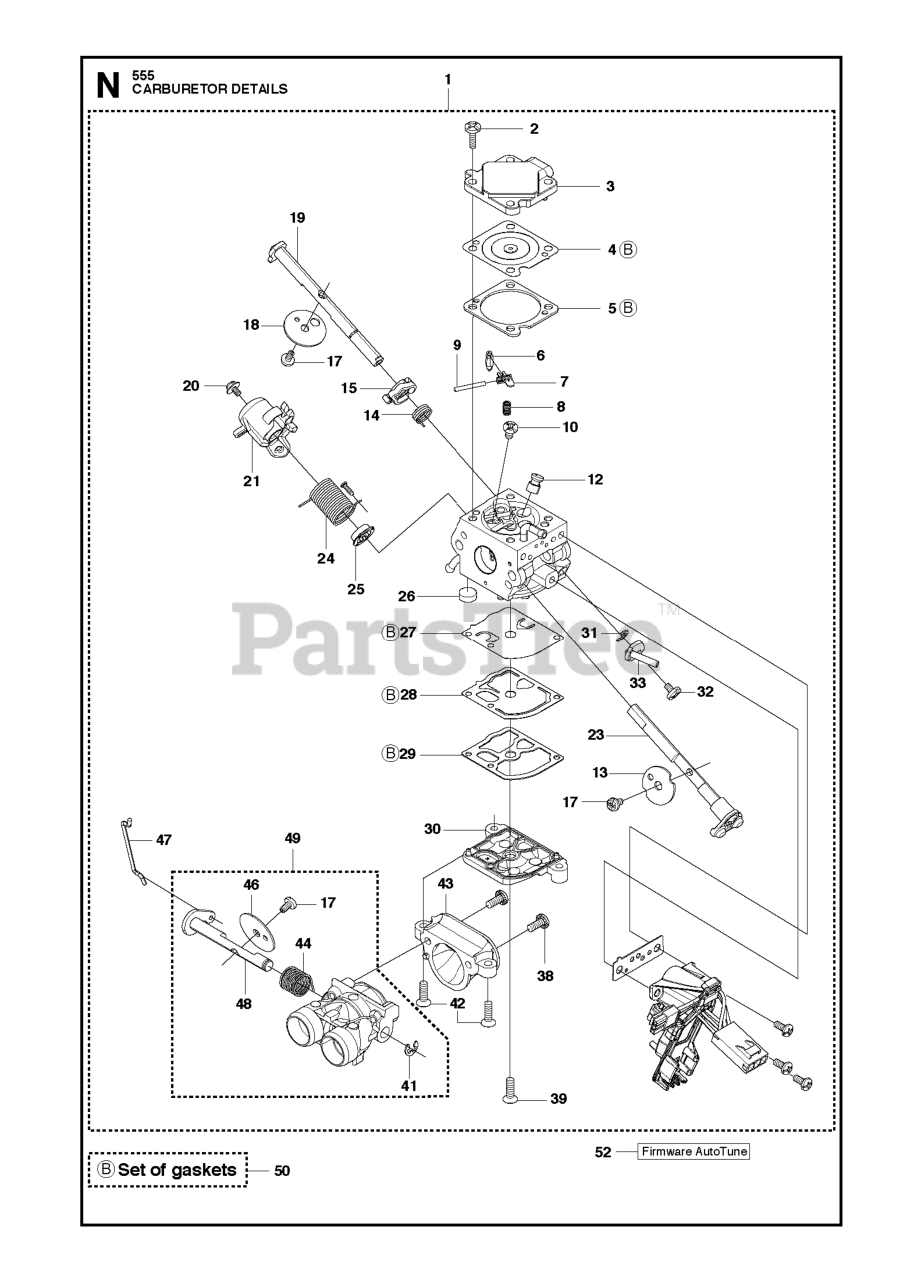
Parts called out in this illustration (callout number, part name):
1	CARBURETOR KIT 555 AUTOTUNE
1	CARBURETTOR KIT 60CC
6	INLET NEEDLE
9	PIN RETAINING SCREW
12	MAIN NOZZLE
13	VALVE
13	THROTTLE VALVE
18	CHOKE VALVE
19	SHAFT ASSY
21	THROTTLE LEVER
23	THROTTLE SHAFT
27	PUMP DIAPHRAGM
33	CHOKE LEVER
46	THROTTLE FLAP
48	SHAFT ASSY
49	THROTTLE VALVE ASSY
50	KIT GASKET AND DIAPHRAM
